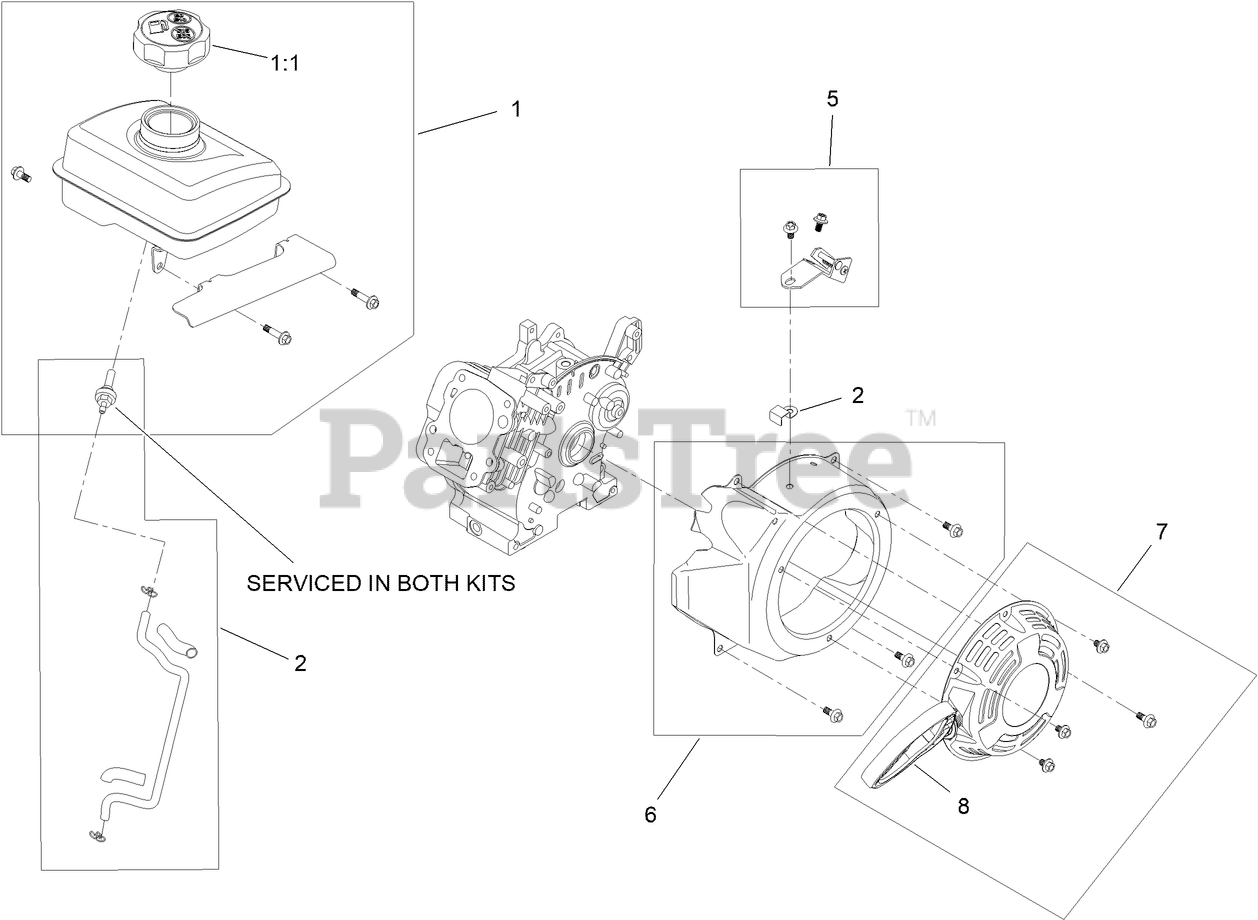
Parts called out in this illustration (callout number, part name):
1	FUEL TANK AND CAP KIT
1:1	CAP-FUEL
2	FUEL LINE KIT
5	GOVERNOR KIT
6	BLOWER SHROUD KIT
7	RECOIL ASM KIT
8	HANDLE-RECOIL
